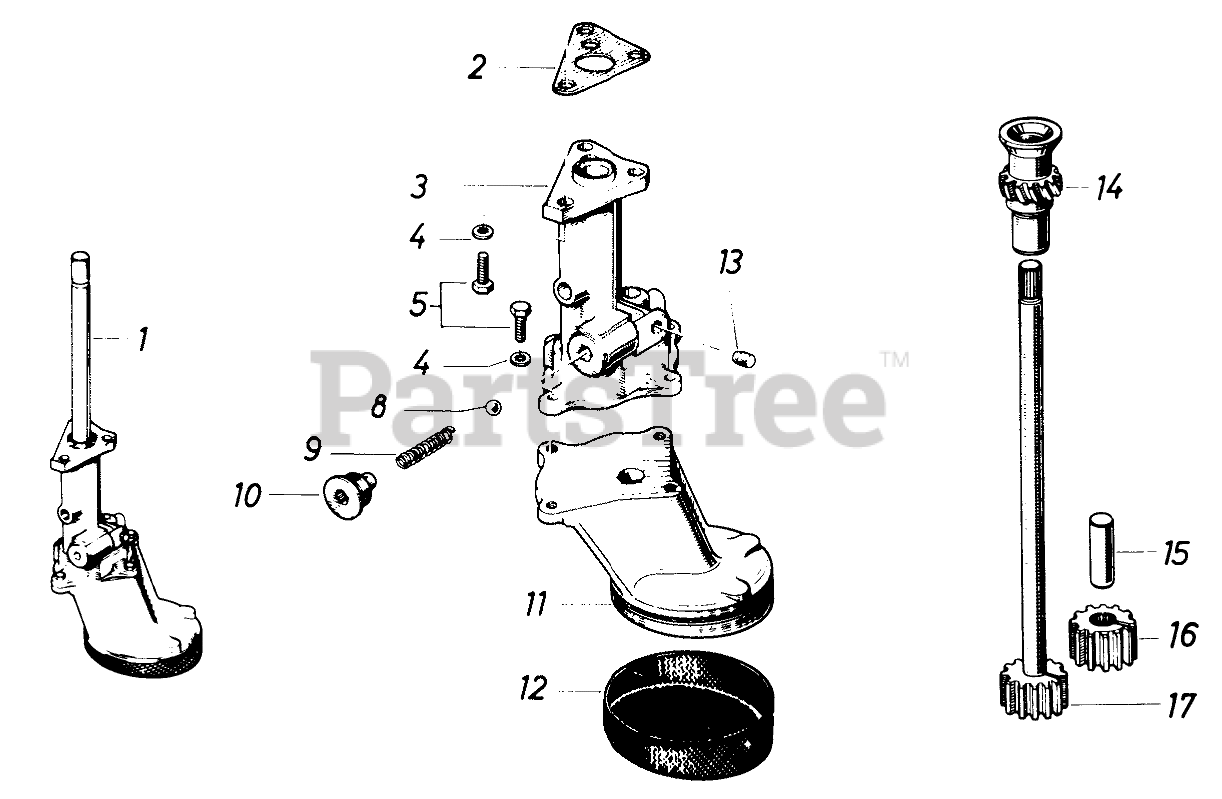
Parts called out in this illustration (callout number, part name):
1	Oil Pump Cpl.
2	Paper Gasket
3	Pump Housing
4	Lock Washer
9	Spring
11	Intake Housing
12	Screen
14	Drive Gear
15	Shaft
16	Pinion
17	Drive Axle
